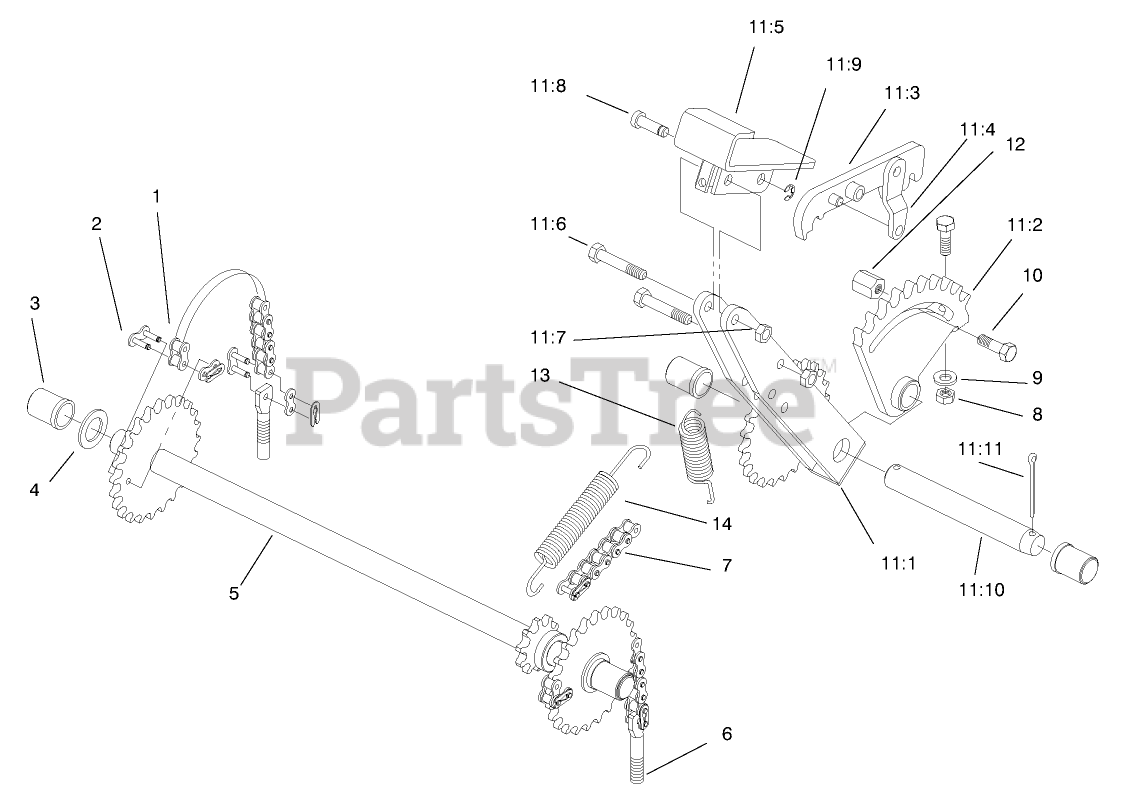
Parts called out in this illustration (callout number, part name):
1	CHAIN-DECK LIFT
2	MASTER LINK CHAIN
3	BEARING-FLANGED
4	WASHER
5	ASM-Sprocket
6	EYE-BOLT 3/8-16X2.50
7	CHAIN-FOOT PEDAL DR
8	NUT-LOCK, NI
9	WASHER-PLAIN
10	SCREW-HH
11	ASM-Deck Hgt Control
11:1	ASSY-LVR ARM 1022 B
11:2	HEIGHT CONTROL SP B
11:3	LIFT-ARM PWL B
11:4	PIVOT-LINK B
11:5	PEDAL-FOOT 10218- B
11:6	SCREW-HH
11:7	NUT-LOCK, NI
11:8	PIN-LOCK
11:9	E RING
11:10	PIN-PEDAL
11:11	PIN-COTTER
12	HEX-STOP NUT N-140
13	SPG-NEUTRAL 20217-35
14	SPRING - EXTENSION
